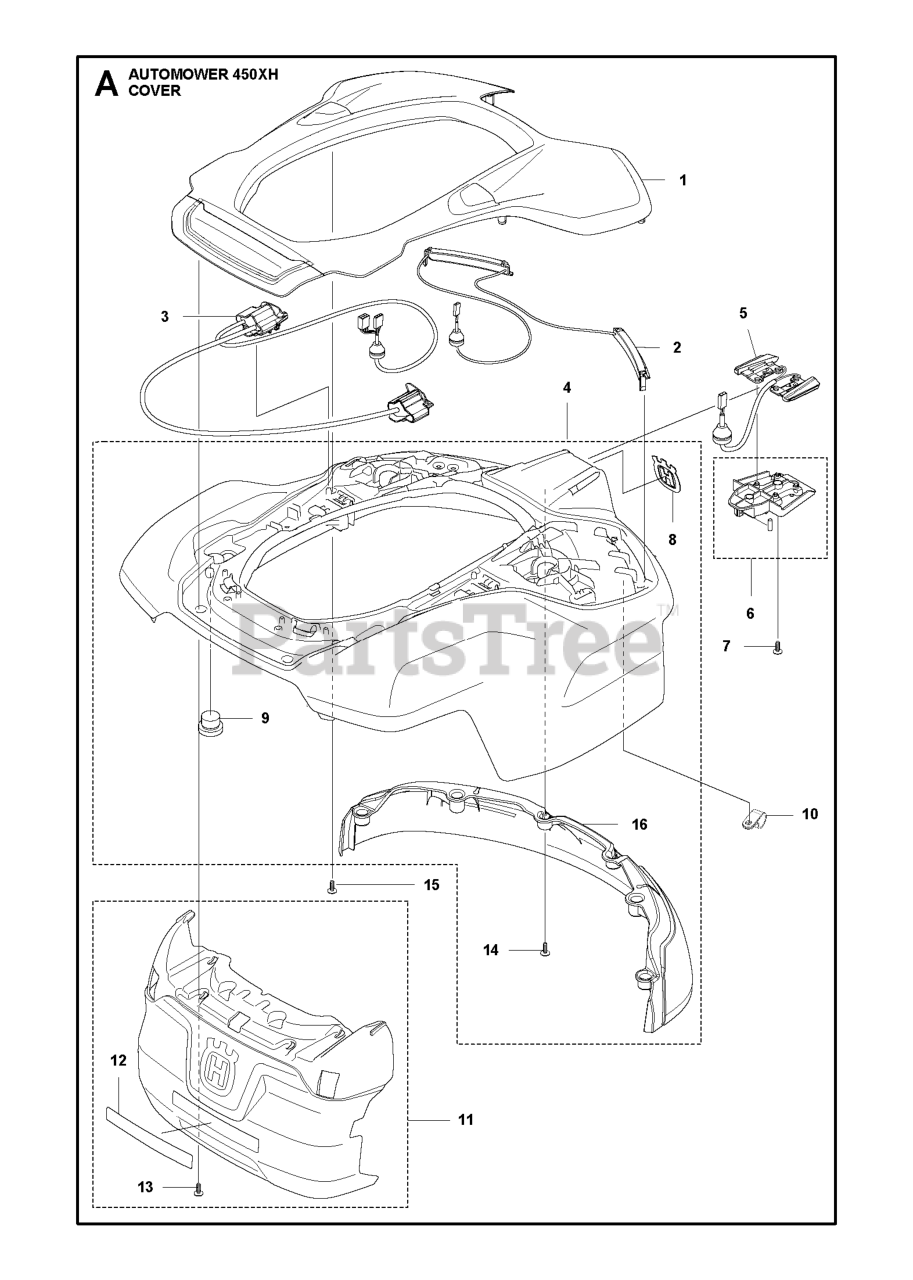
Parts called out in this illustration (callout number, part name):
1	TOP COVER ORANGE/ 450
1	TOP COVER WHITE/ 450
2	WIRING ASSY LED
3	WIRING ASSY ULTRASONIC
4	BODY ASSY 430XH, 450XH
5	CABLE ASSY CHARGING PLATE
6	HOLDER ASSY 430XH, 450XH
7	SCREW 14MM
8	DECAL HUSQVARNA CROWN HEIGHT 5
9	CAP SNAPLOC
10	CLAMP P-CLIP
11	BUMPER ASSY 430XH,450XH,550H
12	LABEL WARNING P15
13	SCREW ITXPANT
14	SCREW ITXPANT
15	SCREW ITXPANT
16	BUMPER FRONT
